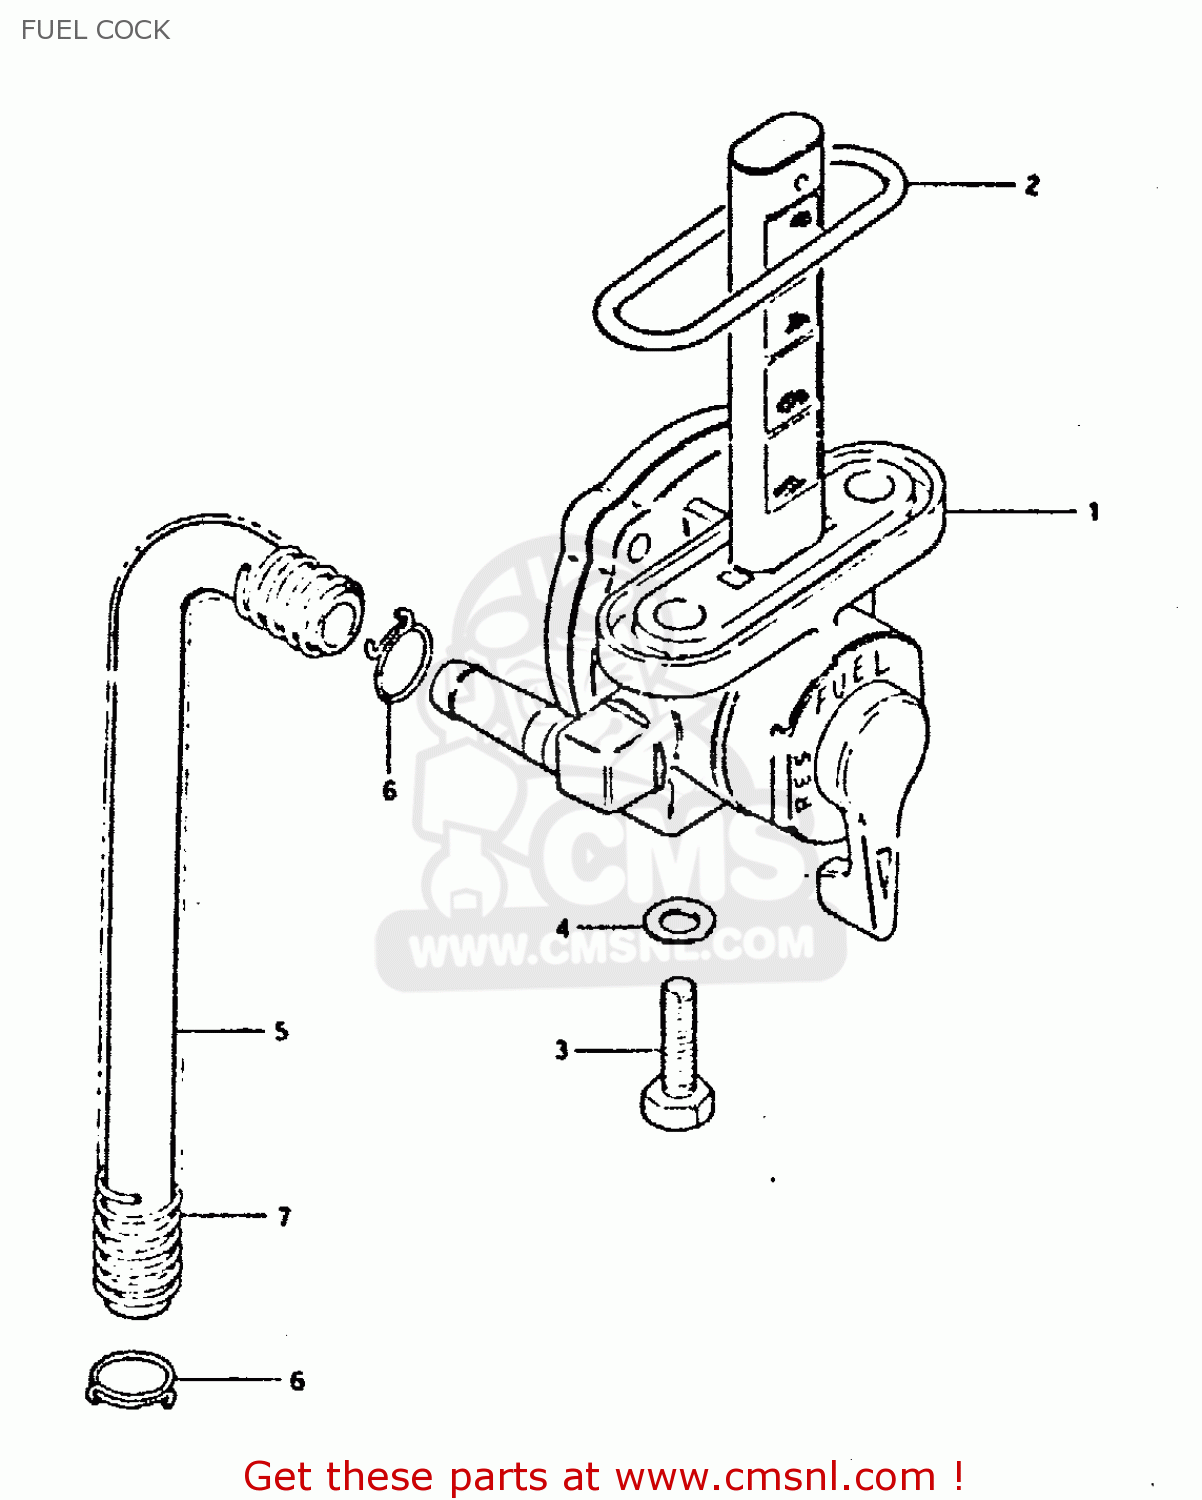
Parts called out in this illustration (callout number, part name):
1	COCK ASSEMBLY,FUEL
2	O RING
3	SCREW
4	GASKET
5	HOSE
6	CLIP
7	SPRING
